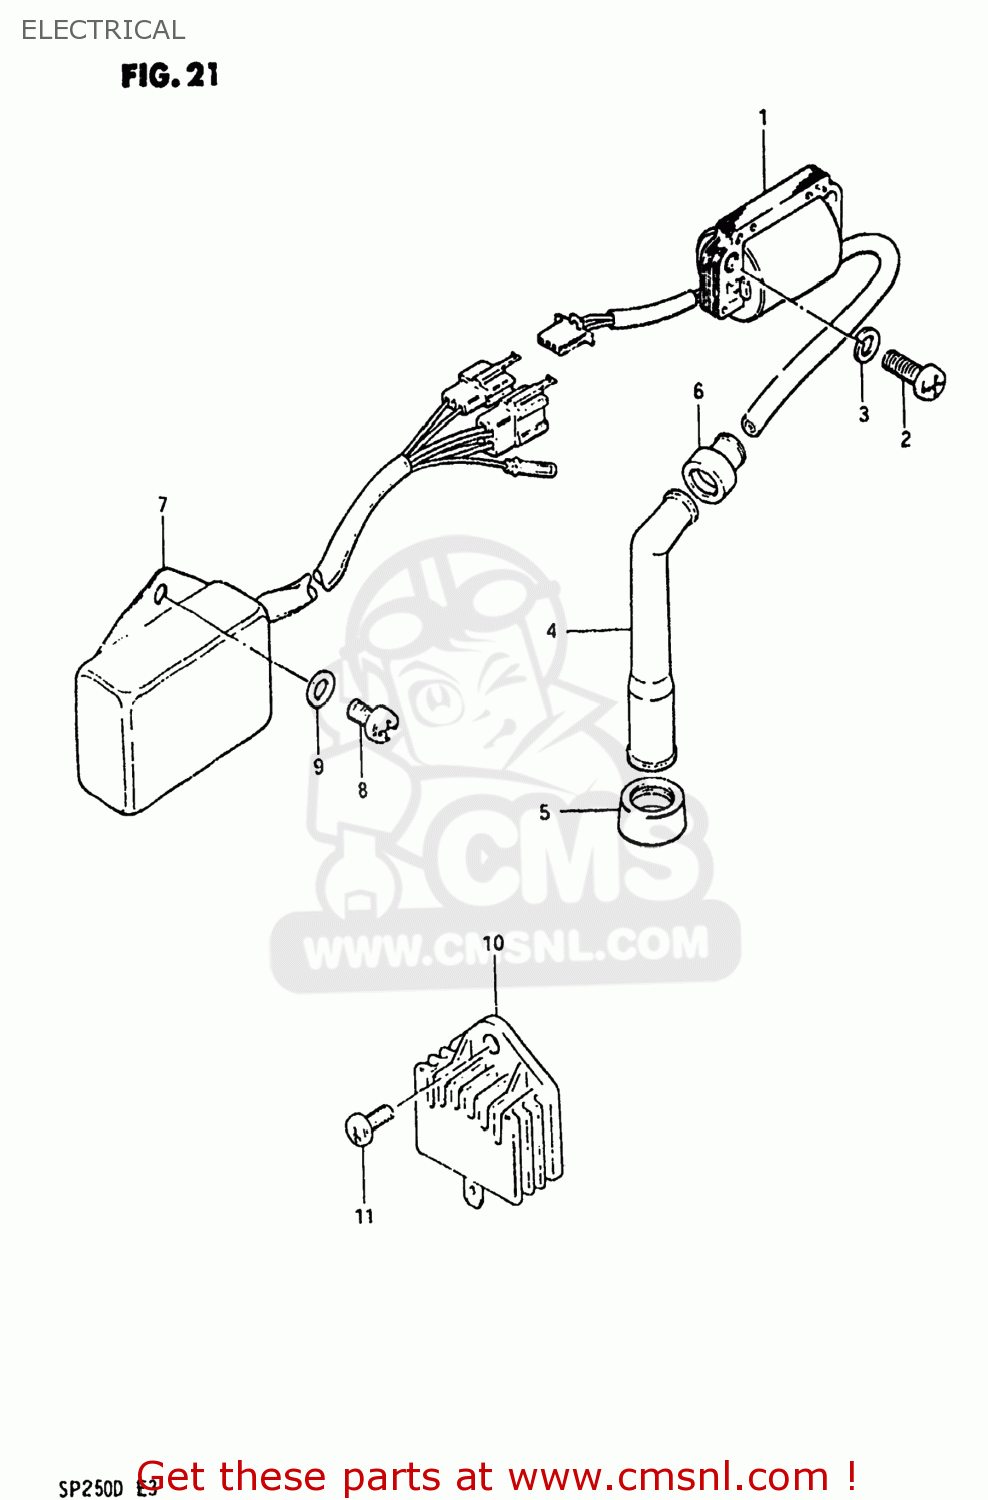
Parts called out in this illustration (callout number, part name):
1	COIL ASSY,IGNITION
2	SCREW
3	LOCK WASHER
4	CAP ASSY,SPARK PLUG
5	SEAL,SPARK PLUG
6	SEAL,SPARK PLU
7	IGNITER UNIT ASSEMBLY
8	SCREW
9	WASHER
10	RECTIFIER ASSY,REGULATOR
11	SCREW 6X12
